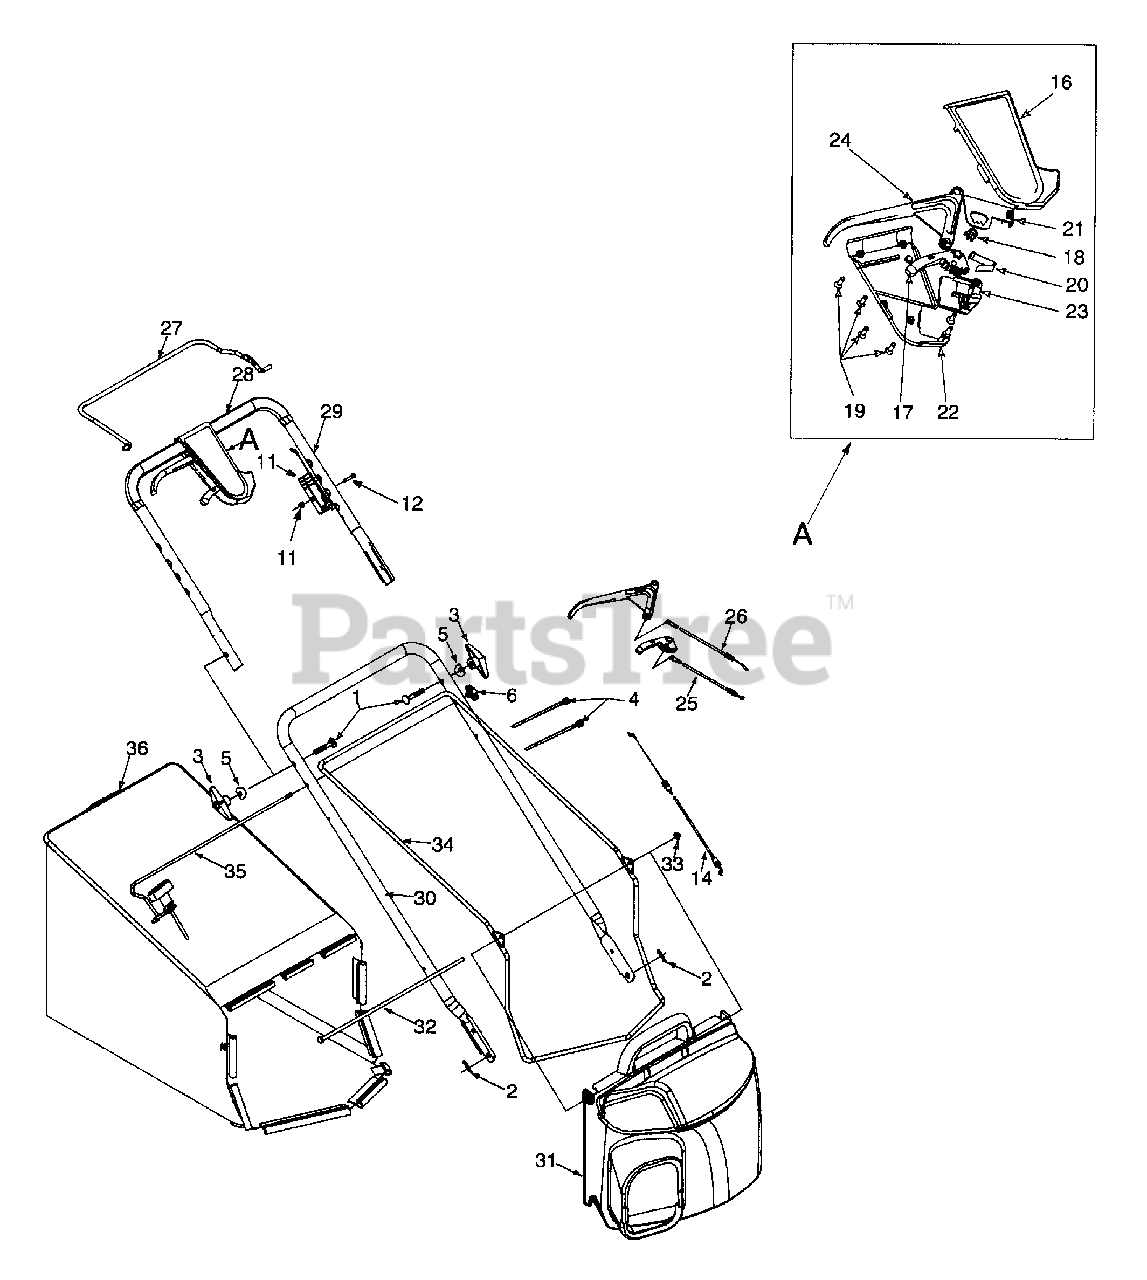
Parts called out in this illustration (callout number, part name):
1	Bolt Cur. Carr. 5/16-18 x 2.0
2	Cotter Pin .072 x 1.12 Lg.
3	Knob Ass'y Wingnut 5/16-18
4	Strap 4.3 Lg.
5	Wash. Sad. .320 1 D x .830 OD
6	Hex Nut 5/16 Thd.
11	Control Cable Box
12	Oval-C-Sunk Screw
14	Control Cable 60" Lg.
16	Upper Control Housing
17	6 Speed Shift Lever
18	Gear Insert
19	C Sunk Tap Screw #10 x .75
20	Shift Lever Spring
21	6 Spd. Rack Cable Brkt.
22	Lower Control Housing
23	Cable Mounting Cap
24	Control Lever
25	6 Spd. Cable
26	S.P Cable
28	Foam Grip (2 Reqd.)
31	Grassbag Cover w/Label
32	Pivot Rod
33	Cap Nut
36	Grassbag
